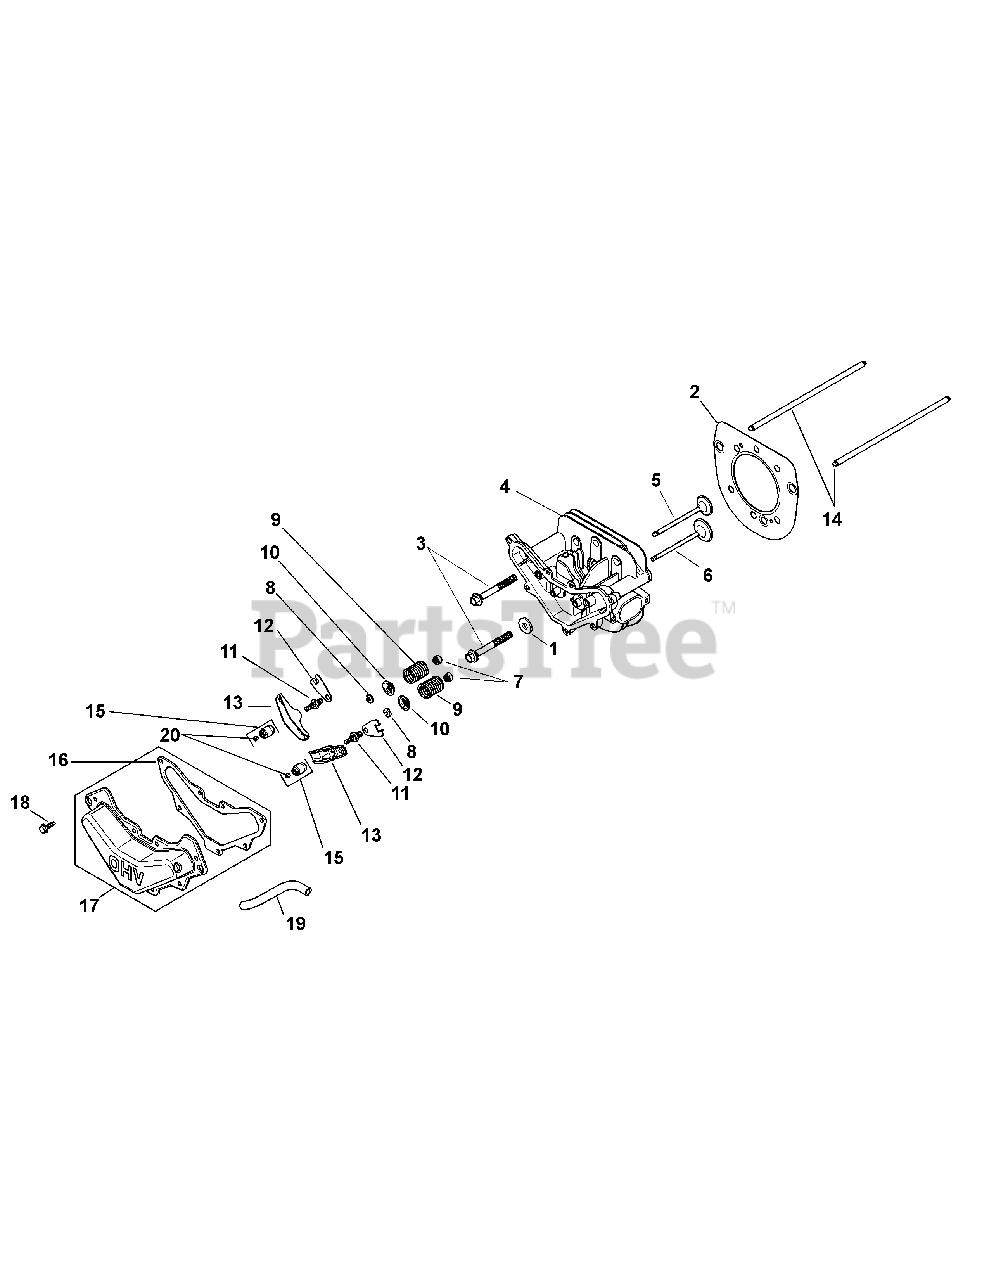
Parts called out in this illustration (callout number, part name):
1	Flat Washer, 13/32
2	Cylinder Head Gasket Kit
3	Flange Screw, M10 X 1.5 X 80
4	Cylinder Head Kit
5	Exhaust Valve
7	Valve Stem Seal
8	Retainer Lock
10	Valve Spring Cap
12	Push Rod Guide Plate
15	Rocker Pivot Assembly
16	Valve Cover Gasket
17	Valve Cover Kit
18	Flg. Thd. Frm. Screw, M6 X 1.0 X 20
19	Breather Hose
